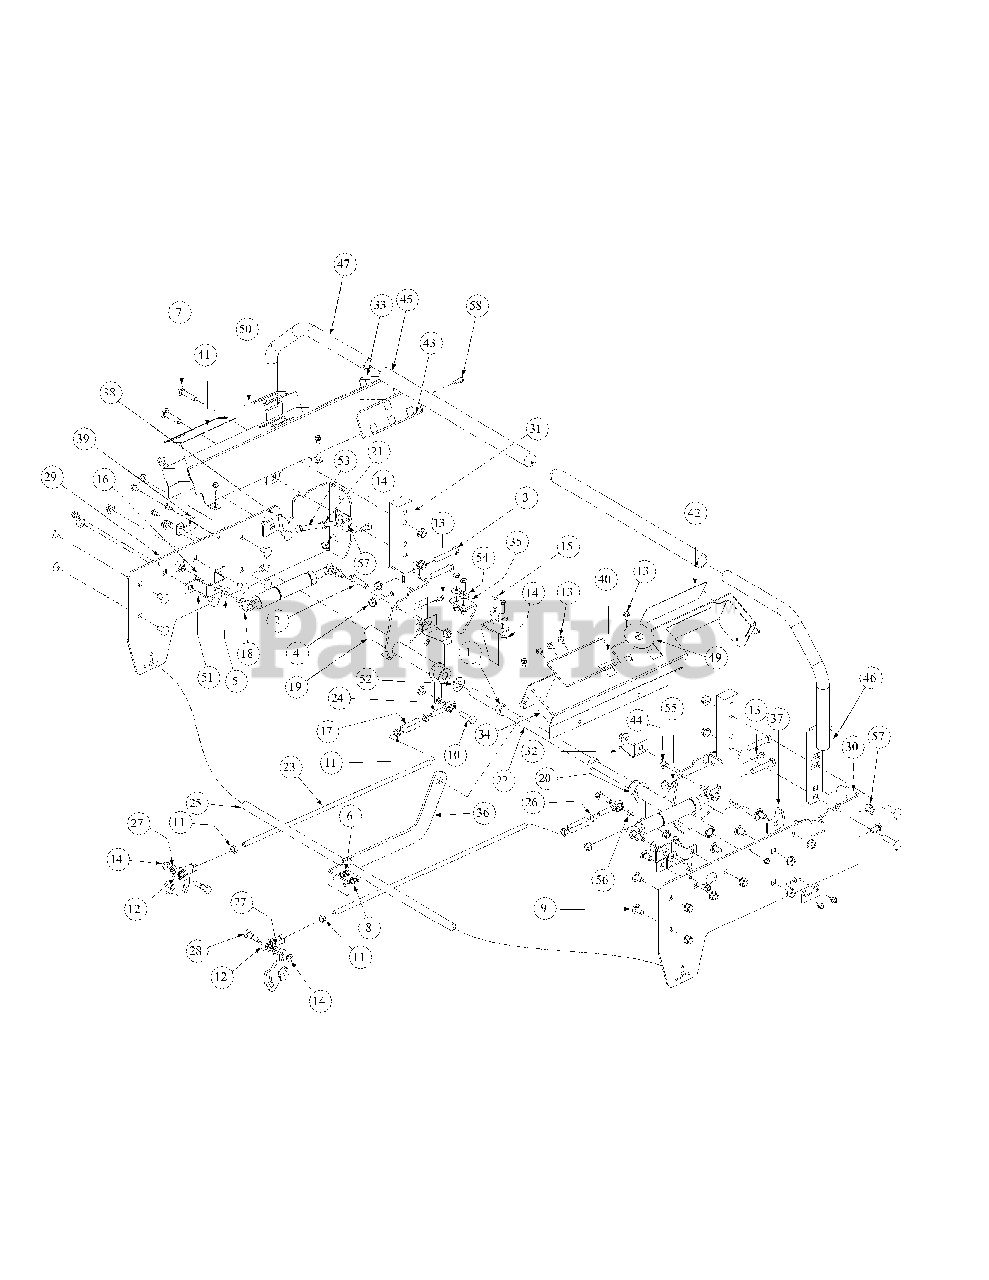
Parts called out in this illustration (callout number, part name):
1	Shaft Collar
2	HHCS, 3/8-16, 1.50
3	HHCS, 3/8-16, 2.50
4	Hex Nut, 3/8-16, Lock Flange
5	External Washer, 3/8
6	HHCS, 1/4-20, .750
7	Hex Carriage Screw, 3/8-16, 1.75
8	Lock Washer, 1/4 Zinc
9	Carriage Bolt, 3/8-16 x .75
10	Capscrew, 3/8-16 x 1-3/4
11	Hex Jam Nut, 3/8-24
12	B/Joint, 3/8-24, Right Hand Female
13	Screw, TT, 1/4-20, 0.5, Hex Index Washer
14	Nut, Lock, Hex Flange, 5/16-18
15	Hex, Cap Screw, 5/16-18 x 3/4
16	Belle Washer, .325 x .930 x .045
17	Turnbuckle
18	Cylinder Return to Neutral
19	Hub Assy, Control LH Bearing
20	Hub Assy, Control RH Bearing
21	Nut, 3/8-16, Jam
22	Shaft Control Brake Steering
23	Rod Connector 3/8 OD x 14.25
24	B/Joint, 3/8-24, Left Hand Female
25	Rear Brake Shaft
26	Nut, 3/8-24, Jam, LH Third
27	Lock Washer, 5/16
28	Screw, Shoulder Control Rod
29	Side Panel, Control, Left
30	Side Panel, Control, Right
31	Mounting Handle
32	Lever, Safety Switch
33	Control Panel, LH
34	Control Panel, RH
35	Switch Mounting Bracket, Lapbar
36	Link Mounting Control Shaft, Bracket
39	Holder Shaft, Park Brake
40	Decal, Right Hand Console
41	Decal, Left Hand Console
42	Decal Right Hand Control
43	Decal, Left Hand Control
44	Nut, Hex, Center Lock, M8
45	Grip, 1.0
46	Lapbar, Weldment, Right Handle
47	Lapbar, Weldment, Left Handle
48	HHCS, 5/16-18 x 1.0
49	Label, Ignition, 2.5 Diameter
50	Label, Control, Throttle and Choke
51	Bracket Assembly, Mount Dampener
52	Flat Washer, 5/8 Nylon
53	HHCS, 3/8-16, 3.00
54	Flat Washer, 5/16
55	Grease Fitting, 90 degree
56	Spacer, .385ID x .625 OD x .50 Lg
57	U-Nut, 3/8-16, .75
58	Screw, TT, 1/4-20 x .750
